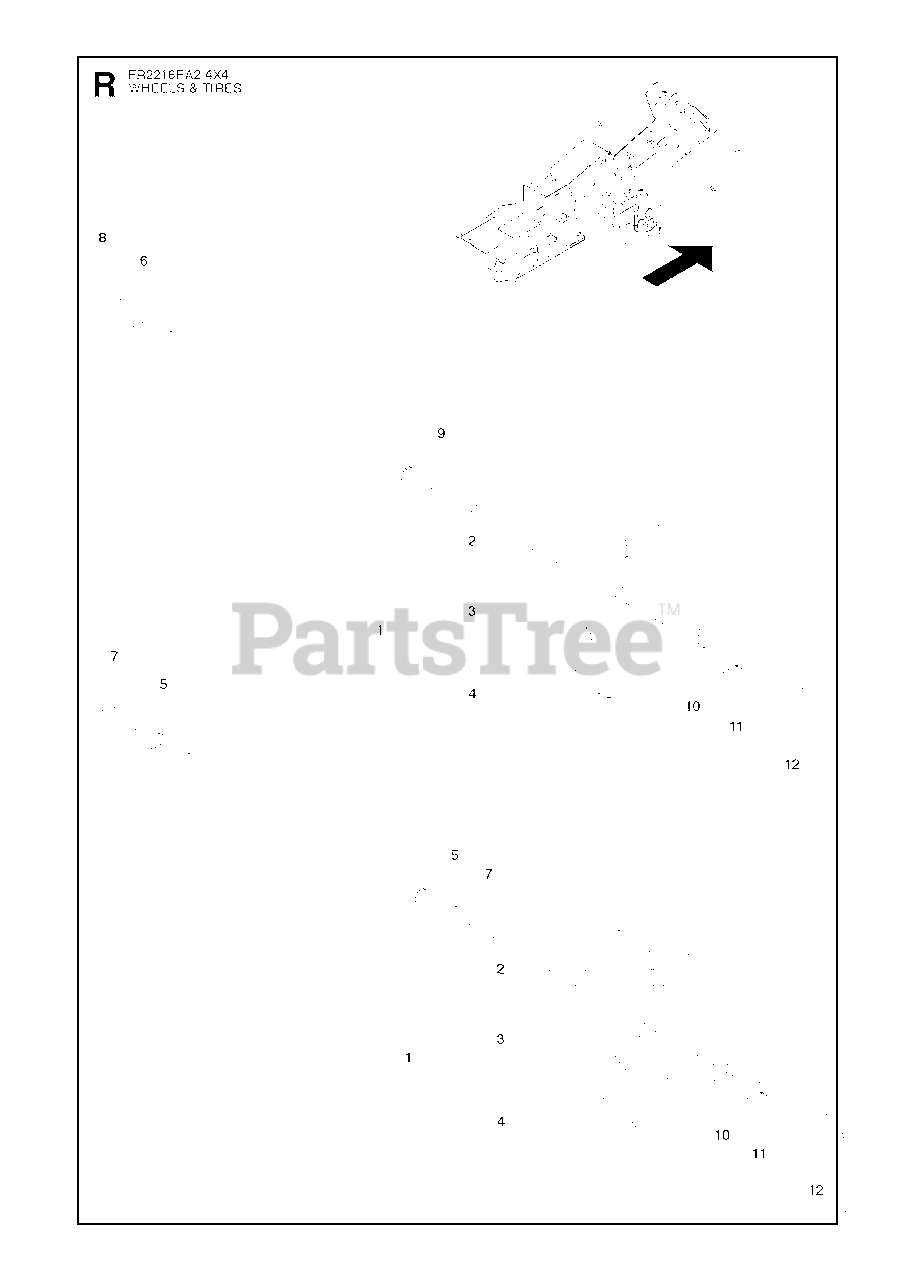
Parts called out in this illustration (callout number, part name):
2	RIM
7	SPACE SLEEVE
11	RETAINING RING
